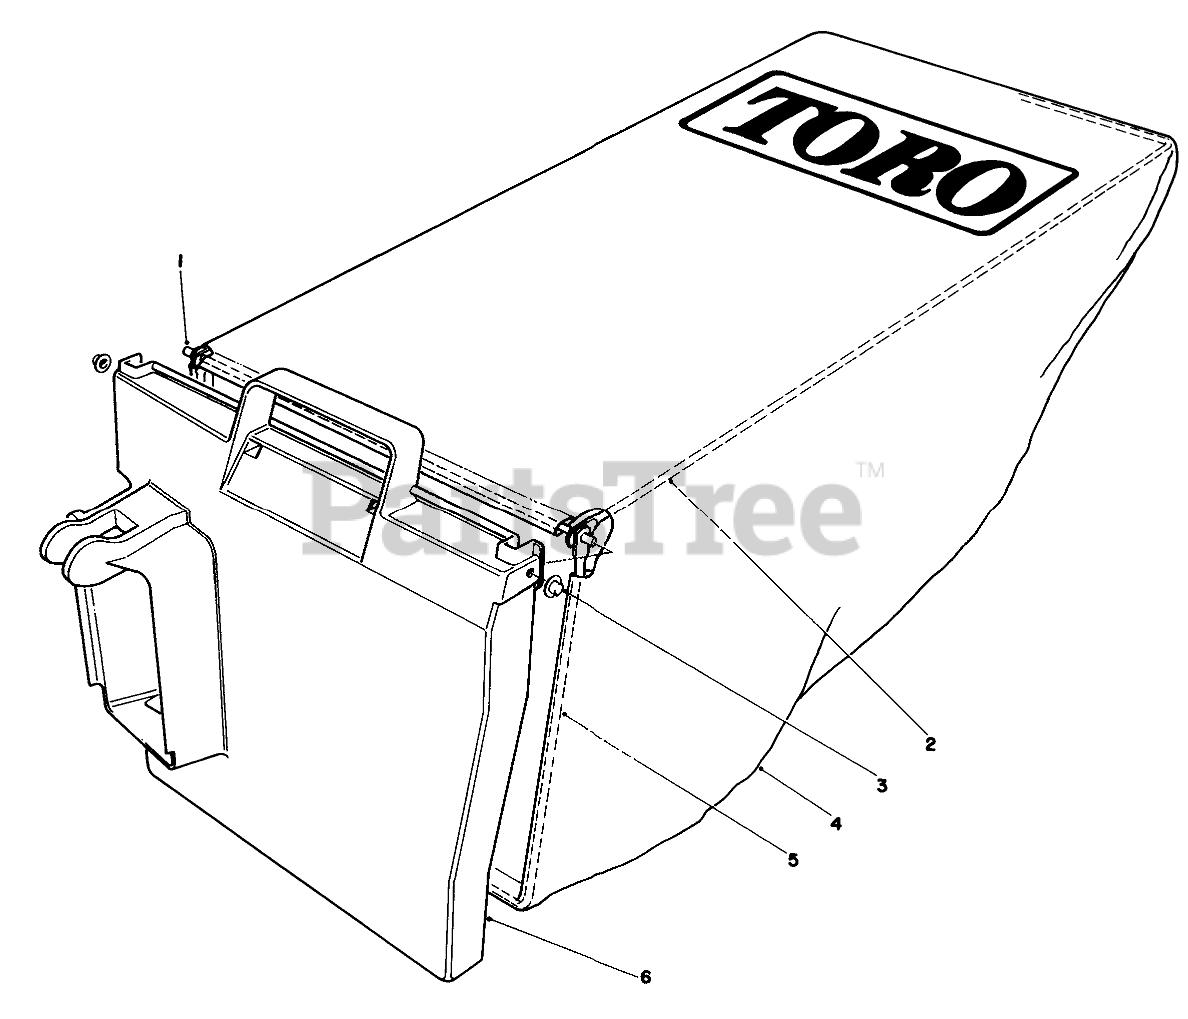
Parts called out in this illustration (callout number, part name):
1	HINGE PIN
2	BAG FRAME-UPPER
3	NUT-PUSH
4	18 BAGGER BAG 33-4552
5	Frame Bag
6	Door-Bag
